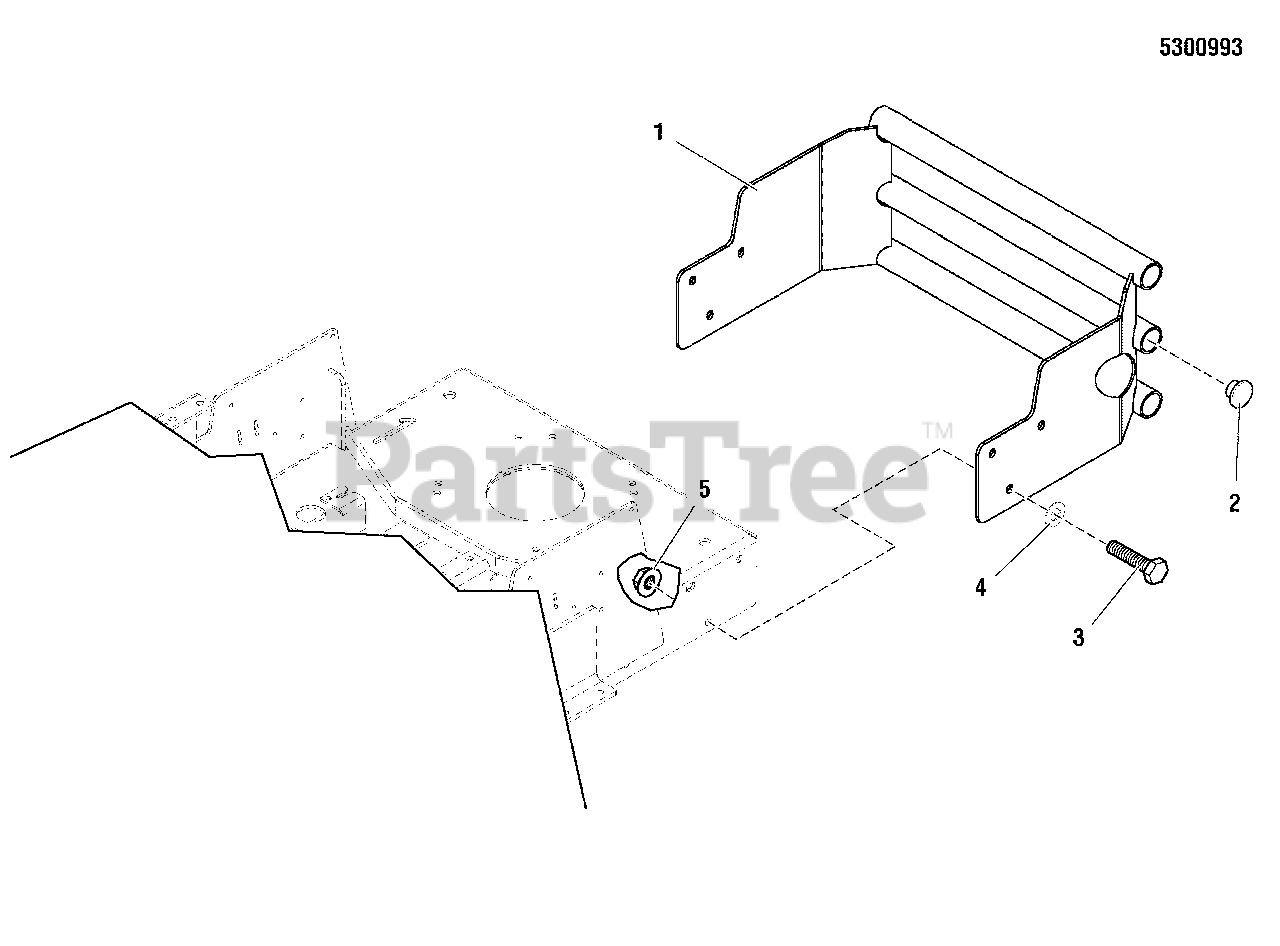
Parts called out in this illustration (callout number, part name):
1	WELD, BUMPER - CONS Z - SNP RED
2	PLUG, PANEL, 1.25 - BLACK
3	BOLT, 3/8-16 X 1" GD5 CZ
4	WASHER, 3/8 SAE
5	NUT, 3/8-16 HEX NYLOCK FLANGE
